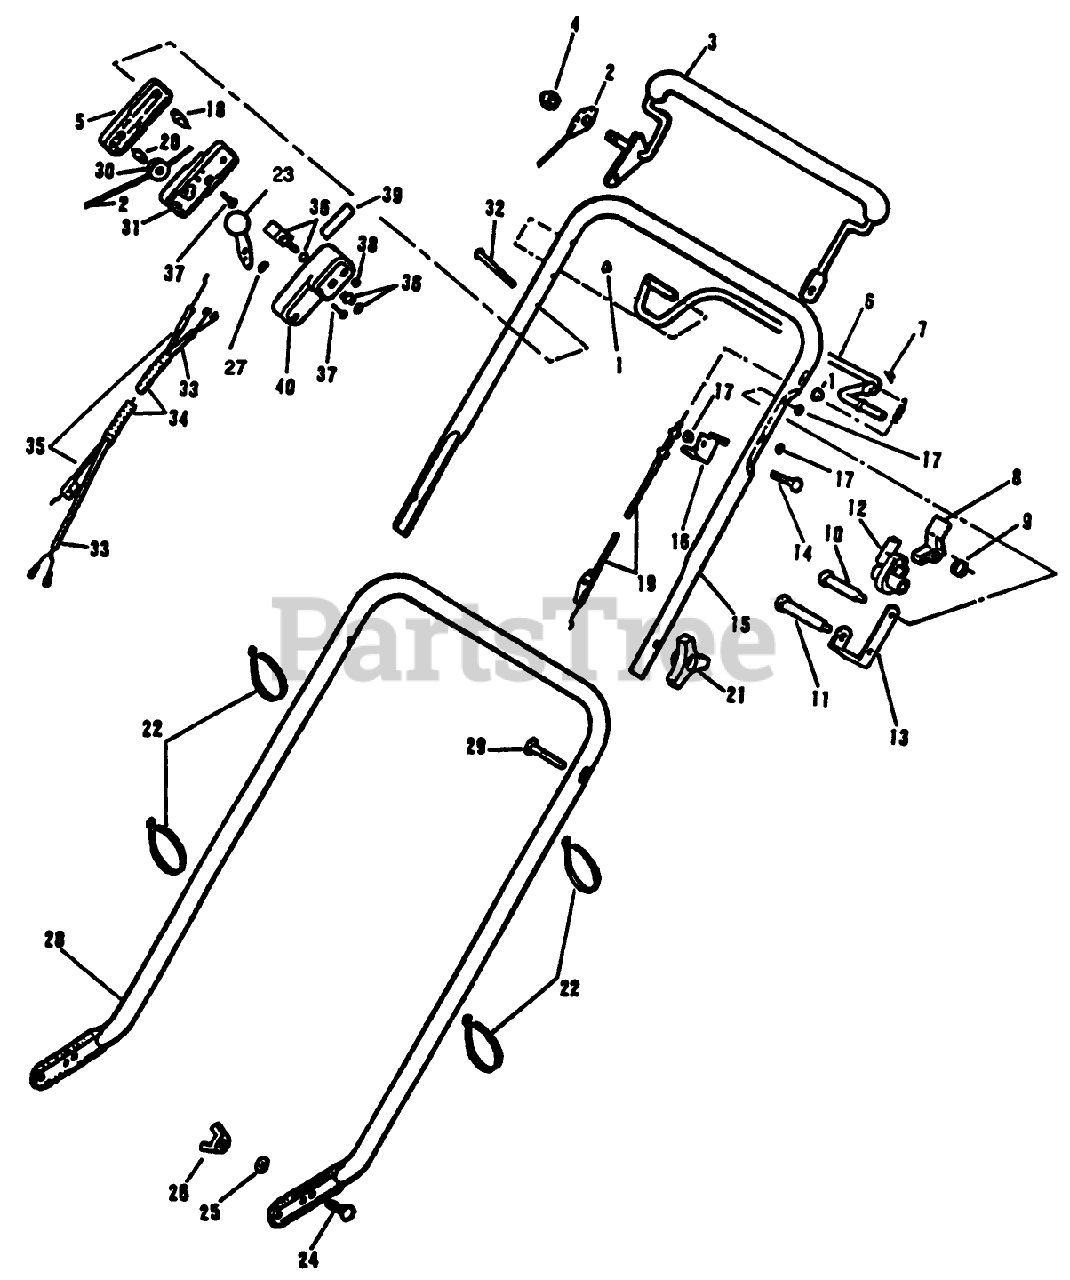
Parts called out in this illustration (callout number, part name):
2	CONTROL CABLE WES
4	NUT ACORN
5	OUTER CONTROL CASE
8	Stop-Latch Lever
11	BOLT
14	SCREW - USE 137-3042
16	ANCHOR C'DUIT TRO
17	LOCKNUT E
18	COLUMN
19	CABLE - CONTROL
20	PIN SKF
22	TIE-CABLE
23	LEVER&KNOB AY WES
26	NUT WING
27	WASHER-SPRING
30	PULLEY PL
32	SCREW
35	CABLE TH'TTLE WES
37	SCREW
38	NUT C/LOCK E
